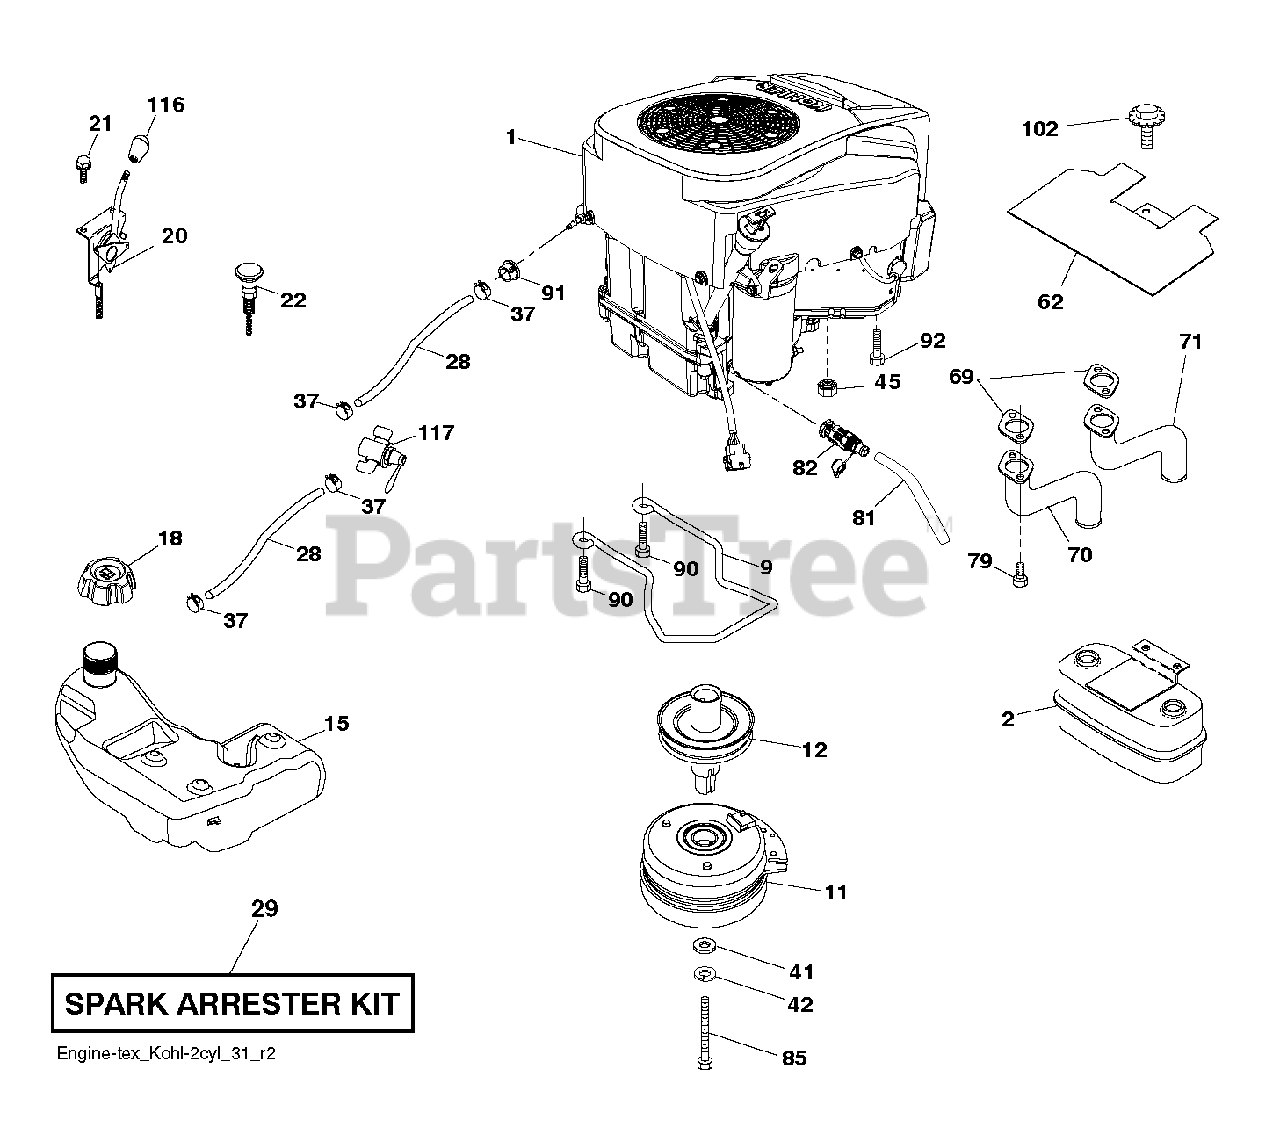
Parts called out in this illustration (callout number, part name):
2	Muffler Assembly, Twin MN
9	KEEPER.BELT.ENG.4.25"2.BLT.431
11	CLUTCH. 5.0 PD. 2.5 OFFSET
12	PULLEY.EXTENDED.SHAFT.GROUND
15	TANK.ASM.FUEL.4R.GAL.EPA.17
18	CAP ASSY FUEL 3" GRAY
20	THROTTLE.KOHL.PRO.#88PAD_46"
21	SCREW.#10X.750
22	CONTROL.CHOKE.ERGO.PUSH-IN.BLA
28	Fuel Hose, 1/4" Low Perm
29	KIT.SPARK ARRESTOR 794945 B&S
37	HOSE CLAMP
42	WASHER 7/16 LOCK
45	NUT
62	SHIELD.HEAT.MUFFLER
69	GASKET.EXHAUST.KOHL.CV18-CV26
70	PIPE.EXHAUST.LH.CV18/20
71	PIPE.EXHAUST.RH.CV18/20
79	SCREW.SOCKET HD.5/16-1
81	TUBE, DRAIN OIL ASM.
82	VALUE.OIL.DRAIN
85	BOLT.HEX.7/16-20X5.GR5.GREEN
90	SCREW 3/8-16X1
91	BUSHING.1.375OD
92	SCREW 3/8-16X1
102	SCREW
116	KNOB - SHIFT
117	VALVE FUEL RESERVE
